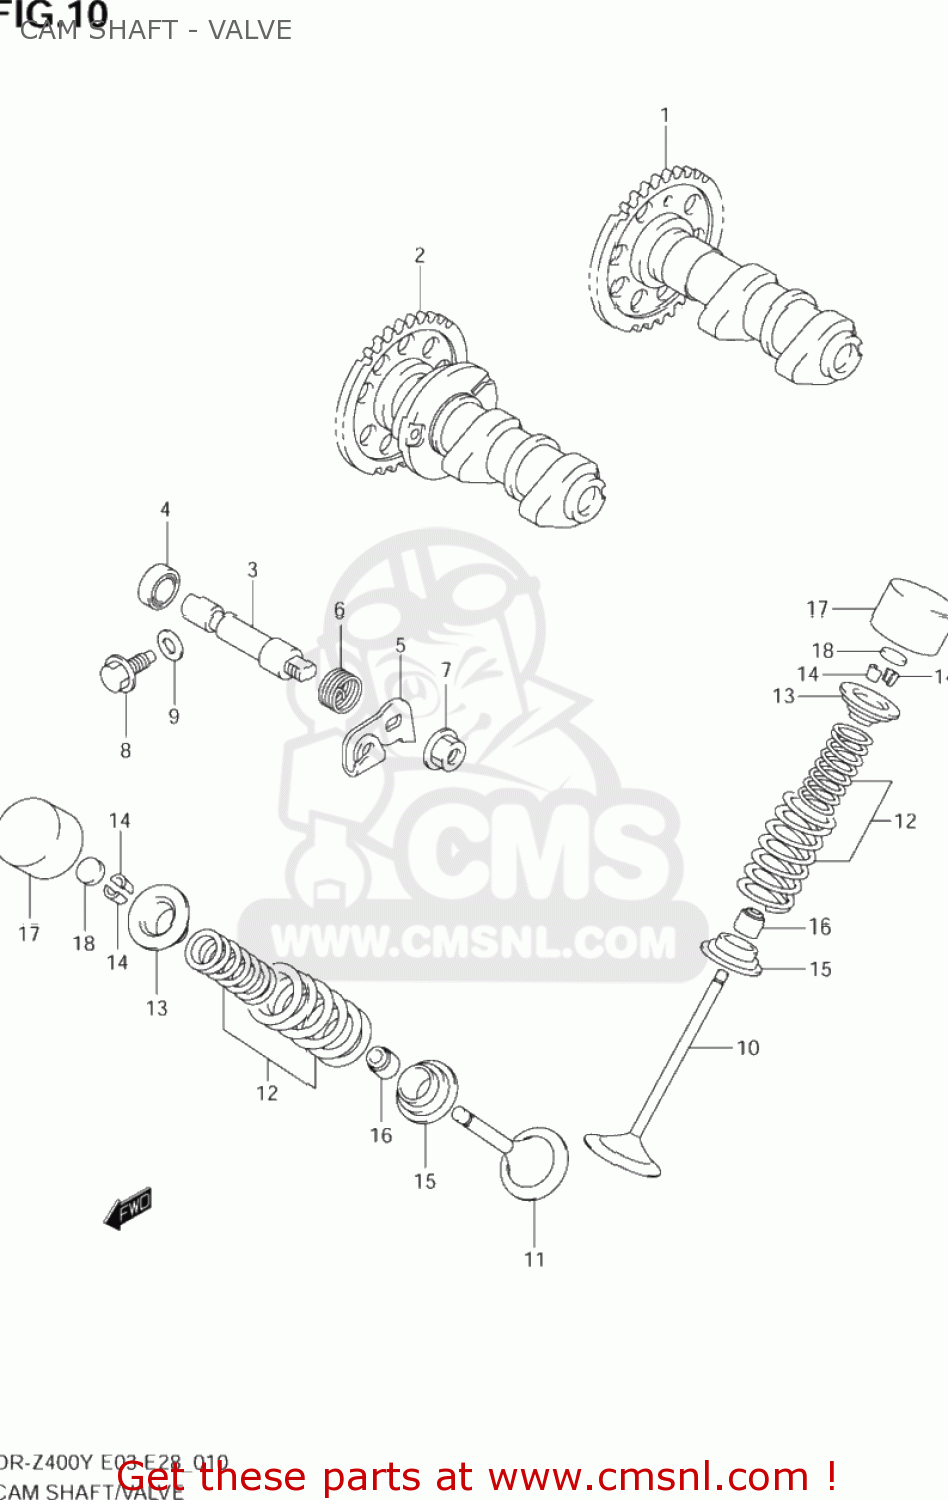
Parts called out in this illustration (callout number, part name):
1	CAMSHAFT,INTAKE
2	CAMSHAFT COMP,EXHAUST
3	SHAFT,DECOMP
4	SEAL,OIL(10X17X6)
5	LEVER,DECOMPRESSION SHAFT
6	SPRING
7	NUT
8	BOLT 6X12
9	GASKET(5.8X13X1.2) (NAS)
10	VALVE,INTAKE
11	VALVE,EXHAUST
12	SPRING SET,VALVE
13	RETAINER,VALVE SPRING
14	COTTER VALVE
15	SEAT,VALVE SPRING
16	SEAL,OIL(5X10X9.7)
17	TAPPET
18	SHIM,TAPPET(T:2.3)
19	SHIM SET,TAPPET
20	CASE,TAPPET SHIM
